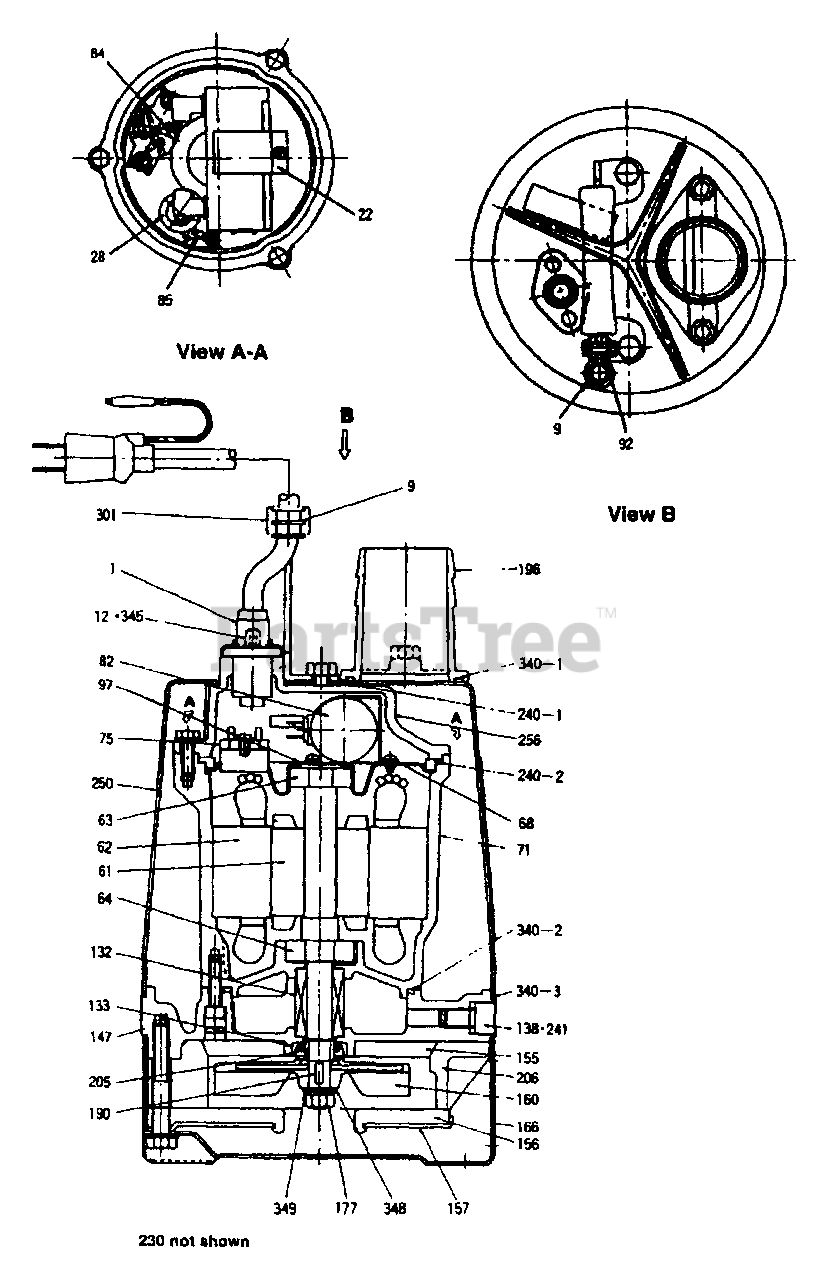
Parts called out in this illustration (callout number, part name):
1	Power cable
9	Cable band
12	Cable nut
28	Grommets
63	Ball bearing (Upper)
64	Ball bearing (Lower)
68	Bearing housing
71	Stator casing
75	Motor Protector
82	Capacitor
84	Lead Wire
85	Earth wire
97	Wave washer
132	Shaft seal
133	Oil seal
138	Oil plug
147	Seal bracket
155	Rear over
156	Suction plate
160	Impeller (60 Hz)
163	Suction cover
166	Strainer
177	Impeller nut
190	Parallel key
196	Hose coupling
206	Pump casing
256	Motor cover
340-2	O-Ring
345	Stud bolt
349	Spring Washer
